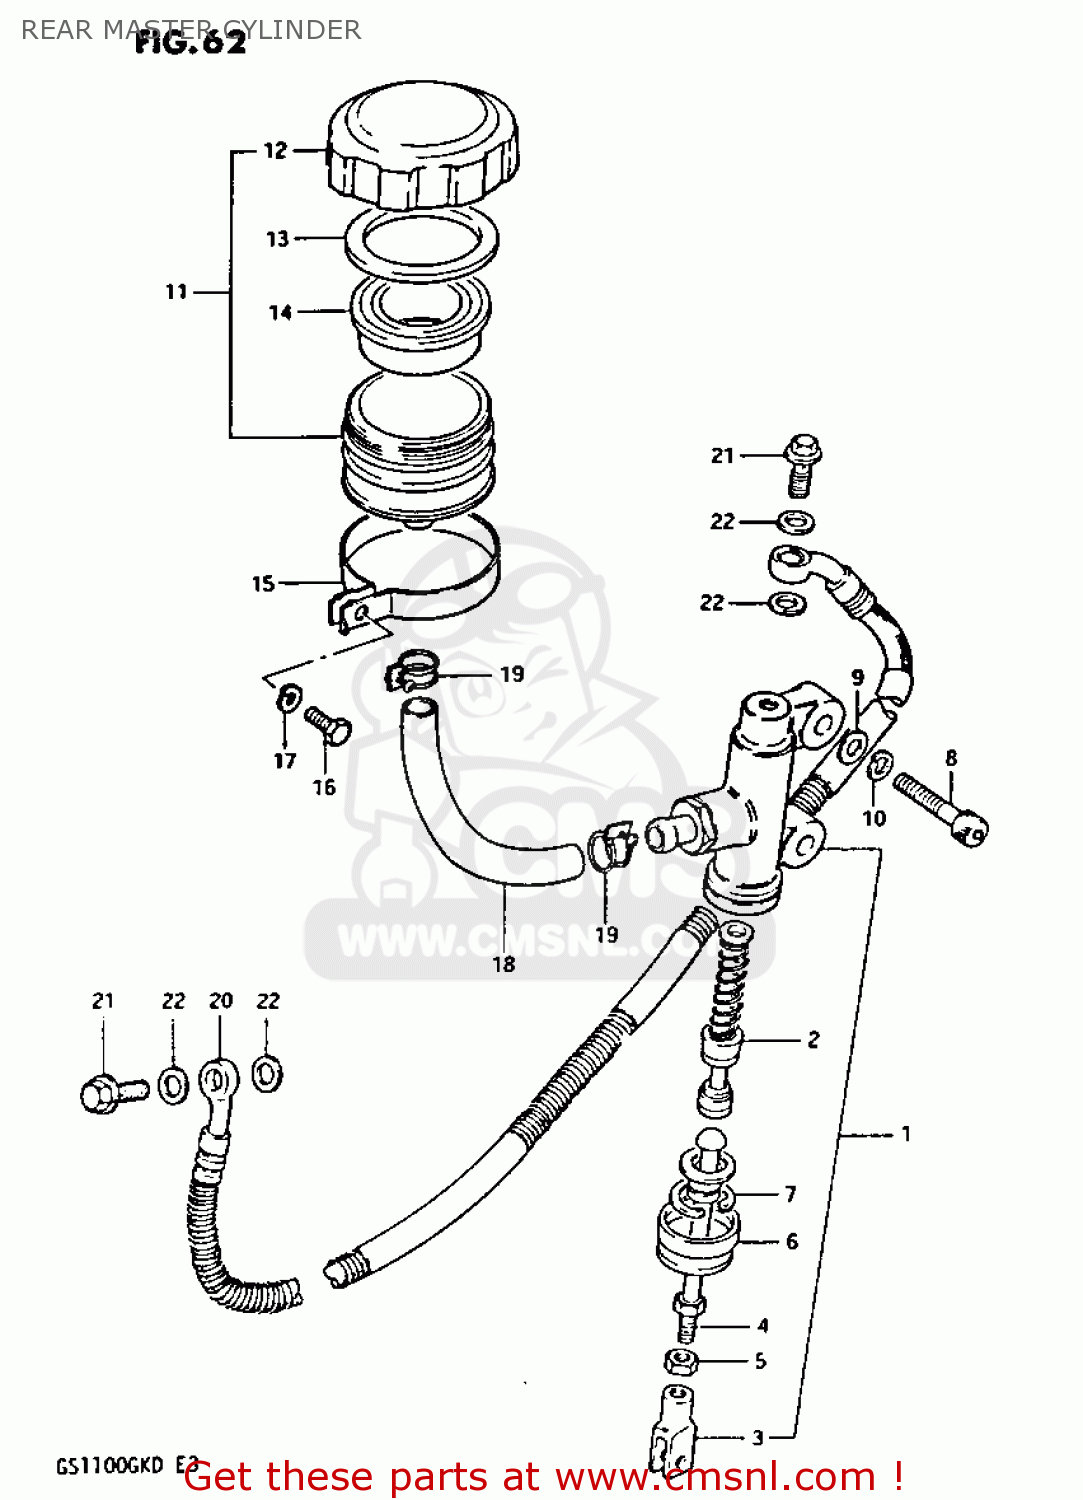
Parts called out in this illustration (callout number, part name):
1	CYLINDER ASSY,RR MASTER
2	PISTON/CUP SET
3	YOKE
4	ROD,REAR MASTER CYLINDER
5	NUT,MASTER CYLINDER
6	BOOT
7	CIRCLIP
8	BOLT, REAR (8X30)
9	WASHER
10	WASHER,LOCK
11	TANK ASSEMBLY,RESERVOIR
12	CAP
13	PLATE,DIAPHRAGM
14	DIAPHRAGM
15	CLAMP
16	BOLT
17	WASHER,LOCK
18	HOSE,RESERVOIR TANK
19	CLAMP
20	HOSE,REAR BRAKE
21	BOLT,UNION
22	WASHER(10X15X1.5)
